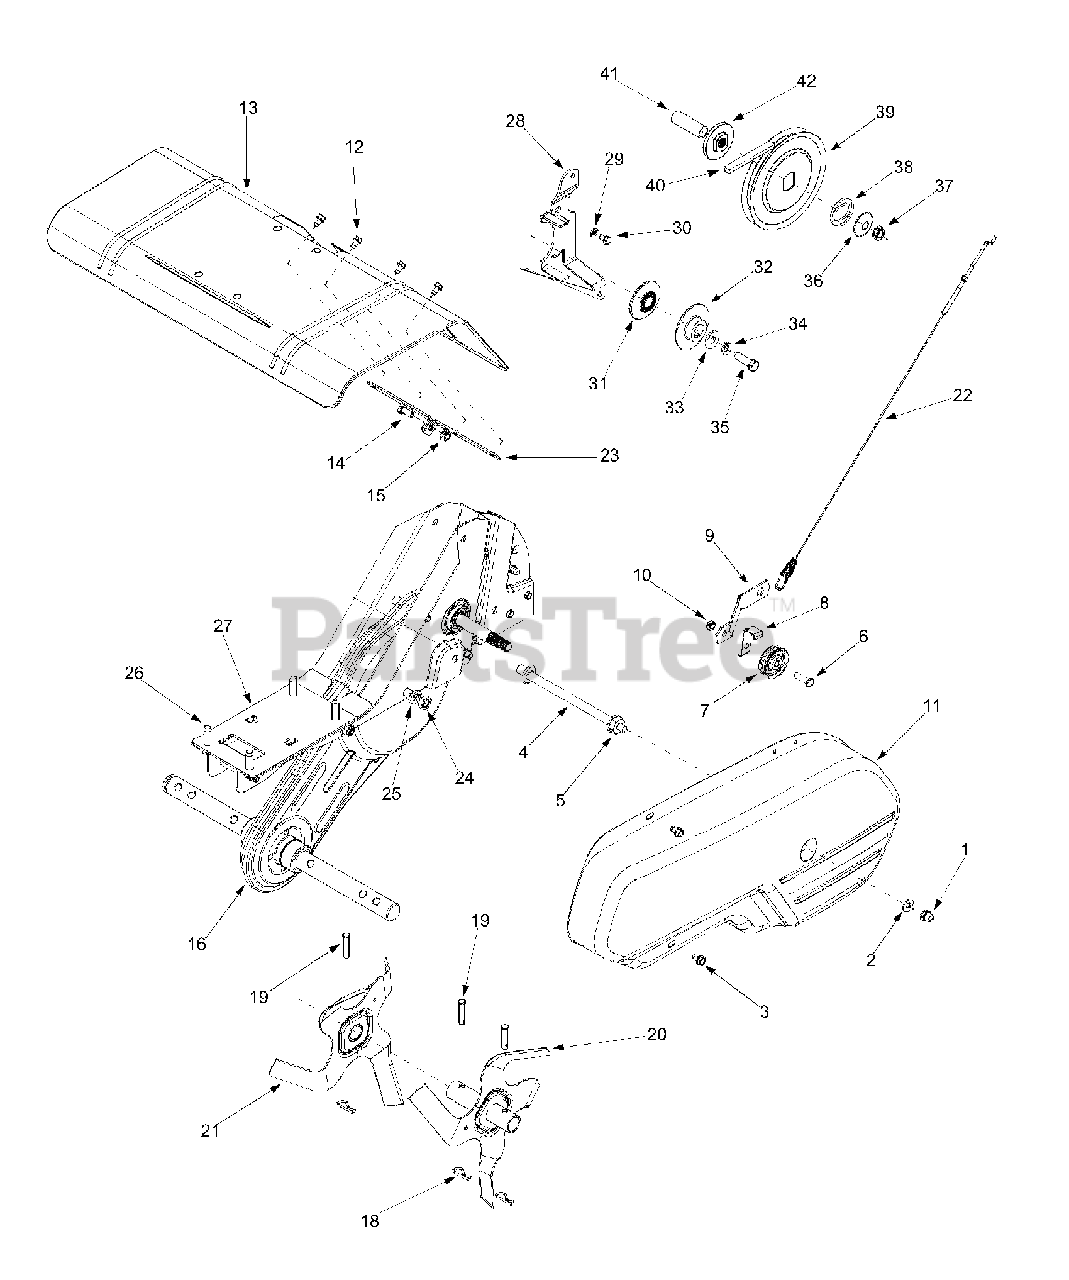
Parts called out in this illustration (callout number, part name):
1	Hex L-Stop nut 1/4-28
2	Flat Wash. .266" I.D. x .625" O.D.
3	Hex Washer Screw 1/4-20 x .5"
4	Belt Cover Bolt
5	Hex Flange Top L-Nut 5/16-18
6	Hex Hd. Scr. 3/8-16 x 1.25" Lg.
7	Fl-Idler 2.12" O.D.
8	Idler Belt Keeper
10	Hex Cent. Jam Nut 3/8-16 Thd.
12	Hex Washer Screw 1/4-20 x .5"
15	Hex Flange Top L-Nut 5/16-18
16	Chain Case Assembly Complete
18	Internal Cotter Pin
19	Clevis Pin
22	Forward Clutch Cable
24	L-Wash. 7/16" I.D.
25	Hex Nut 7/16-20 Thd.
26	Hex Washer Screw 3/8-16 x 1.25"
29	Lock Washer 5/16
30	Hex Bolt 5/16-24 x .5"
31	Inner Engine Pulley Half
32	Outer Engine Pulley Half
33	Flat Washer .385 ID x 1.0 OD
34	Lock Washer 3/8
35	Hex Bolt 3/8-24 x 1.25"
36	Bell-Wash. .525" I.D. x 1.5" O.D.
37	Hex Jam Nut 1/2-20 Thd. (Gr. 5)
38	Retainer Washer Bearing
39	Fl-Pulley 6" Dia.
40	V-Belt (Forward)
41	Spacer .64" Dia. x 2.4" Lg.
42	Pulley Mounting Adapter
